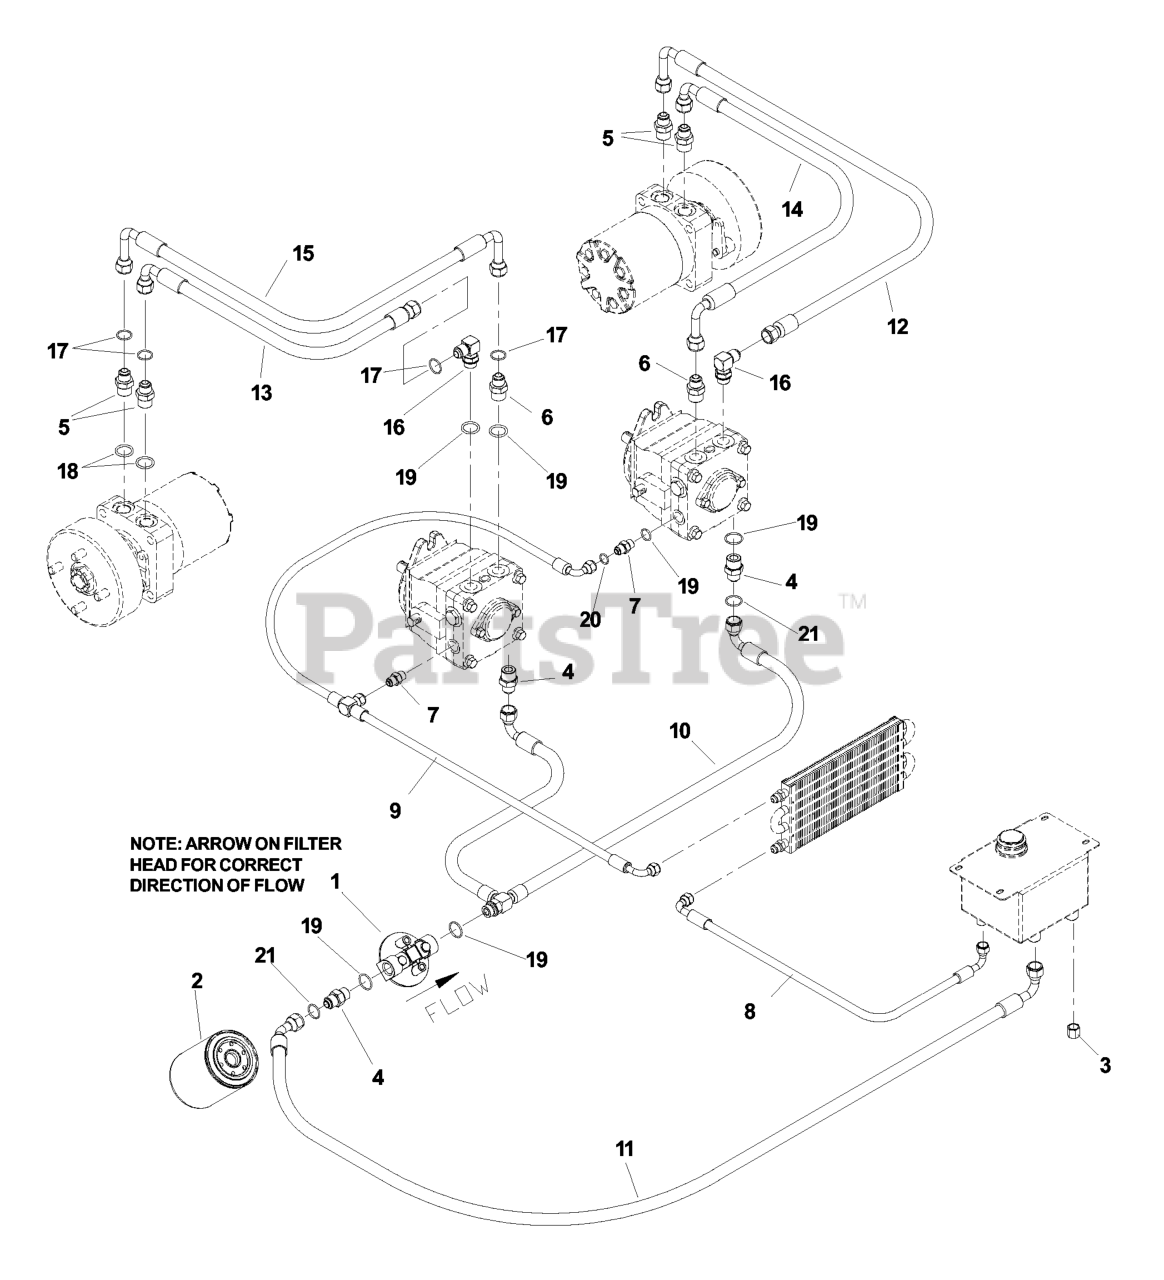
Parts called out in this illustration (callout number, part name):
1	FILTER HEAD
2	HYDRAULIC OIL FILTER
3	NUT 9/16-18 JIC CAP
4	FITTING, STRAIGHT F6400-8-8-0
